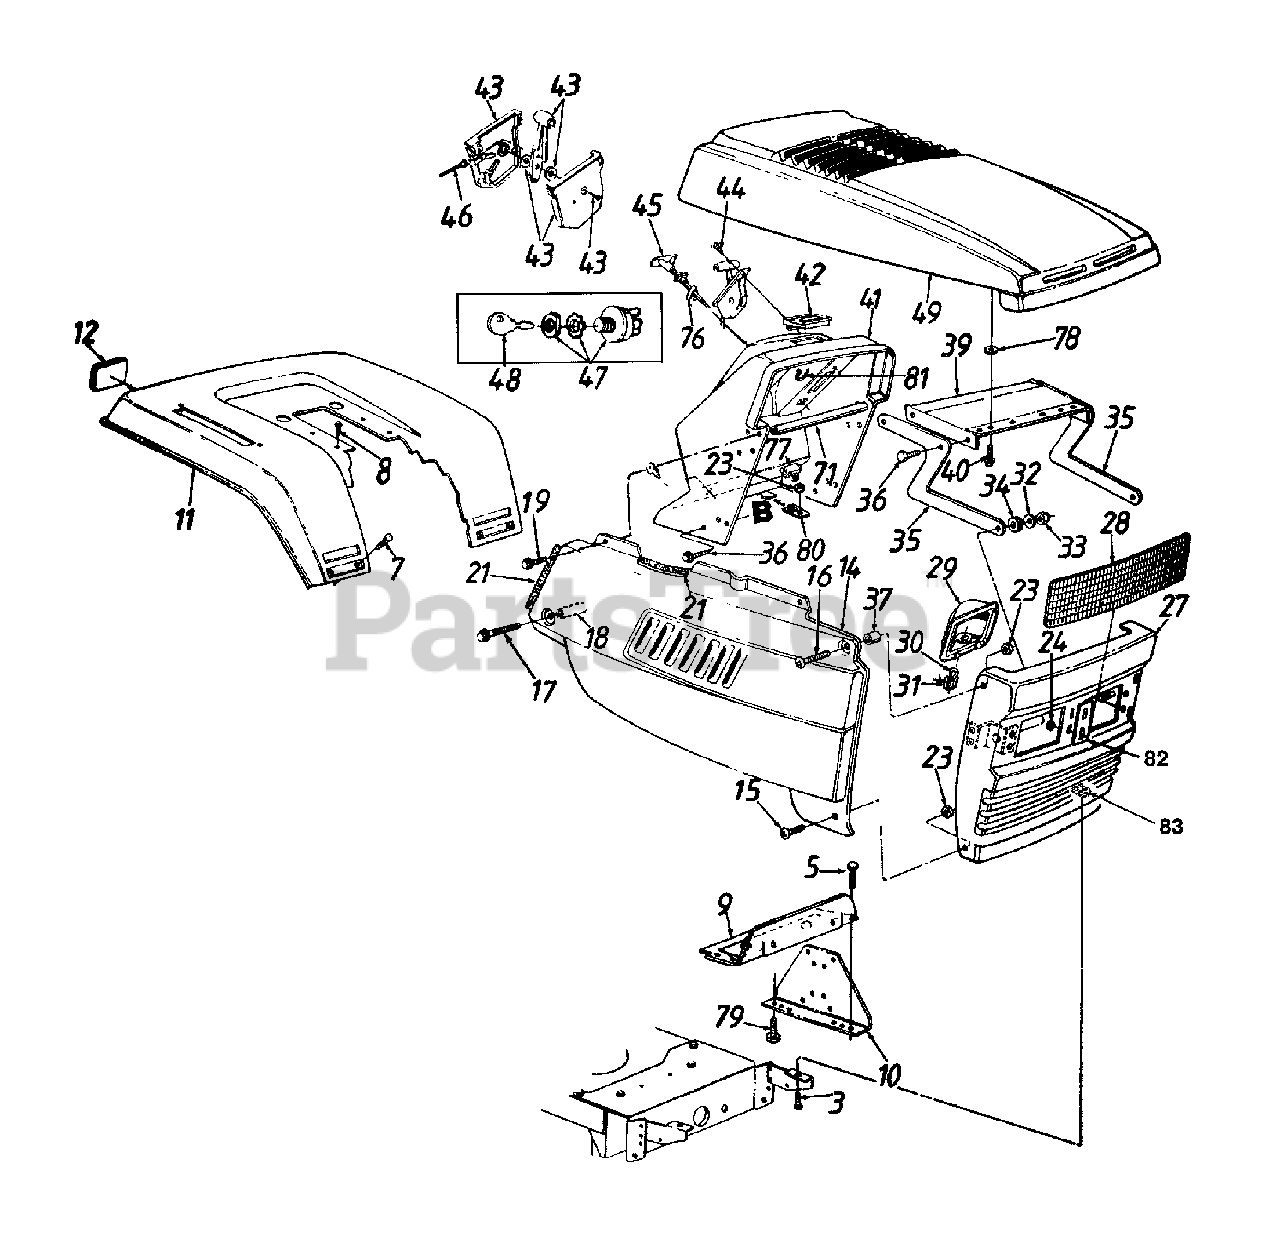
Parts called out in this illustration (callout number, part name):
3	Hex Bolt 5/16-18 x .1" Lg.
5	Hex Wash. Hd. Scr. 5/16" x .5" Lg.
7	Truss Mach. Scr.1/4-20 x .5" Lg.
8	Hex Wash. Hd. Tap Scr. 5/16 x .75" Lg.
16	Truss Mach. Scr. 1/4-20 x 1.0" Lg.
17	Hex Wash. TT-Tap Scr. 1/4-20 x 1.75"
18	Spacer .26" I.D. x 1.32"
19	Hex Rolling Tap Scr. 1/4-20 x.75" Lg.
21	Trim Strip-18" Lg.
23	Hex Sems Nut 1/4-20 Thd.
24	Speed Nut 5/16" Thd.
29	Headlamp Housing
30	Headlamp
31	Twist Lock Lamp Socket
32	BelLock Washer .345" I.D. x .88"
33	Hex Lock Nut 5/16-18 Thd.
34	Rubber Washer
37	Spacer .262" I.D. x .31"
41	Dash
42	Ammeter
43	Throttle Control Box Assembly
44	Mach. Scr. #10 x .44" Lg.
45	Choke Control 23" Lg.
46	Throttle Control Wire 18.5" Lg.
47	Ignition Switch
48	Ignition Key
49	Hood-Red
71	Grille Support Tube
76	Choke Retainer
77	Light Switch
78	Flat Washer .406" I.D. x .812" O.D.
79	Hex Bolt 1/4-20 x .88" Lg.
80	Dash Fastening Tab
81	Cable Tie
82	Chrome Label
83	U-Nut 5/16-18 Thd.
16725-0640	PANEL-SIDE RH - CO-OP GREEN (0640)
16725-0665	PANEL-SIDE RH - YARDMAN GREEN (0665)
16725-0691	PANEL-SIDE RH - BLACK JACK (0691)
17309B-0483	PANEL-SIDE-LH - CHARCOAL GRAY (0483)
17309B-0638	PANEL-SIDE-LH - MTD/TROY-BILT RED (0638)
17458A-0665	PANEL-SIDE RH - YARDMAN GREEN (0665)
17459A-0638	PANEL-SIDE-LH - MTD/TROY-BILT RED (0638)
